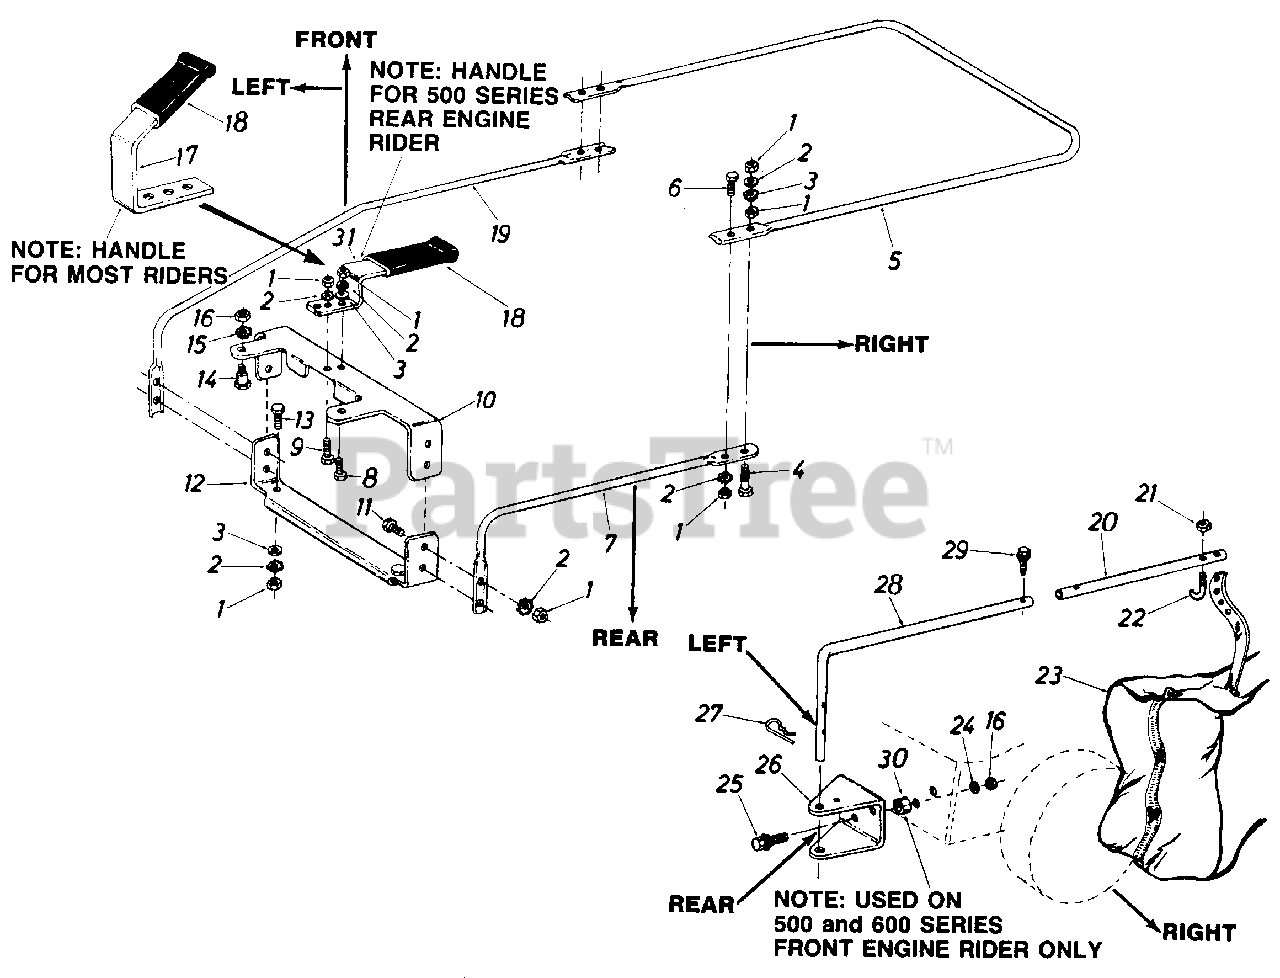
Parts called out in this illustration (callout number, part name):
1	Hex Nut 1/4-20 Thd.
2	Ext. L-Wash. 1/4" I.D.
3	Fl-Wash. .281" I.D. x .5" O.D.
4	Hex Bolt 1/4-20 x 1 5n Lg.
5	Upper Frame Half
6	Hex Bolt 1/4-20 x 1n Lg.
7	Lower Frame Tubing
8	Hex Bolt 1/4-20 x .62n Lg.
9	Hex Bolt 1/4-20 x 35n Lg.
10	Upper Opening Support
11	Hex Bolt 1/4-20 x ln Lg.
12	Lower Opening Support
13	Hex Bolt 1/4-20 x .50" Lg.
14	Shld. Bolt .437 Dia. x .350
15	Ext. L-Wash. 5/16 I.D.
16	Hex Nut 5/16-18 Thd.
19	Lower Frame Arm
23	Grass Catcher Bag
24	L-Wash. 5/16" I.D.
25	Hex Sems Bolt 5/16-18 x .75" Lg.
26	Hitch Bracket
27	Internal Cotter Pin 5/8" Dia.
28	Lower Holding Arm
29	Hex Self-Tap .50" Lg.
30	Spacer
31	Handle
